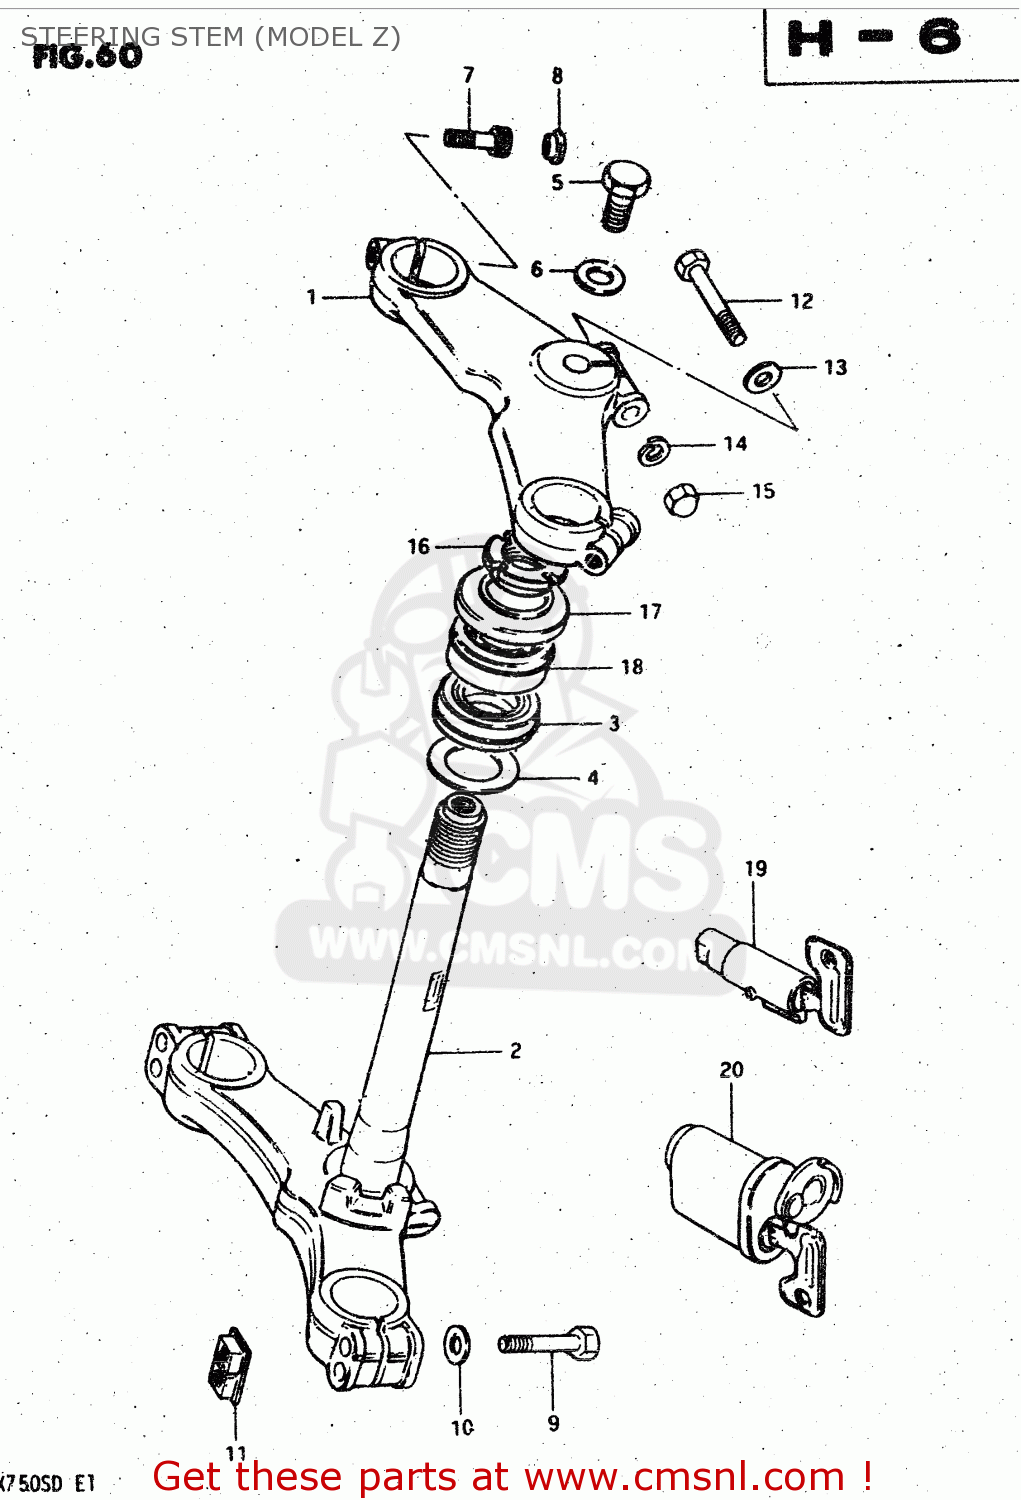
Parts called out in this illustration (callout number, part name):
1	STEM HEAD, STEERING (SILVER)
2	STEM, STEERING (SILVER)
3	BEARING
4	WASHER,THRUST
5	NUT,STEM HEAD
6	WASHER,STEERING STEM B
7	BOLT
8	CAP(OD:20)
9	BOLT 8X55
10	WASHER
11	NUT,FR FORK INNER TUBE
12	BOLT 8X50
13	WASHER
14	WASHER,LOCK,8.
15	NUT
16	NUT,STEERING STEM
17	DUST SEAL,STEERING,UPPER
18	TAPER,ROLLER BEARING
19	LOCK ASSEMBLY,STEERING (NEI
20	LOCK ASSY, STEERING (NEIMAN TYPE EXECUTE
